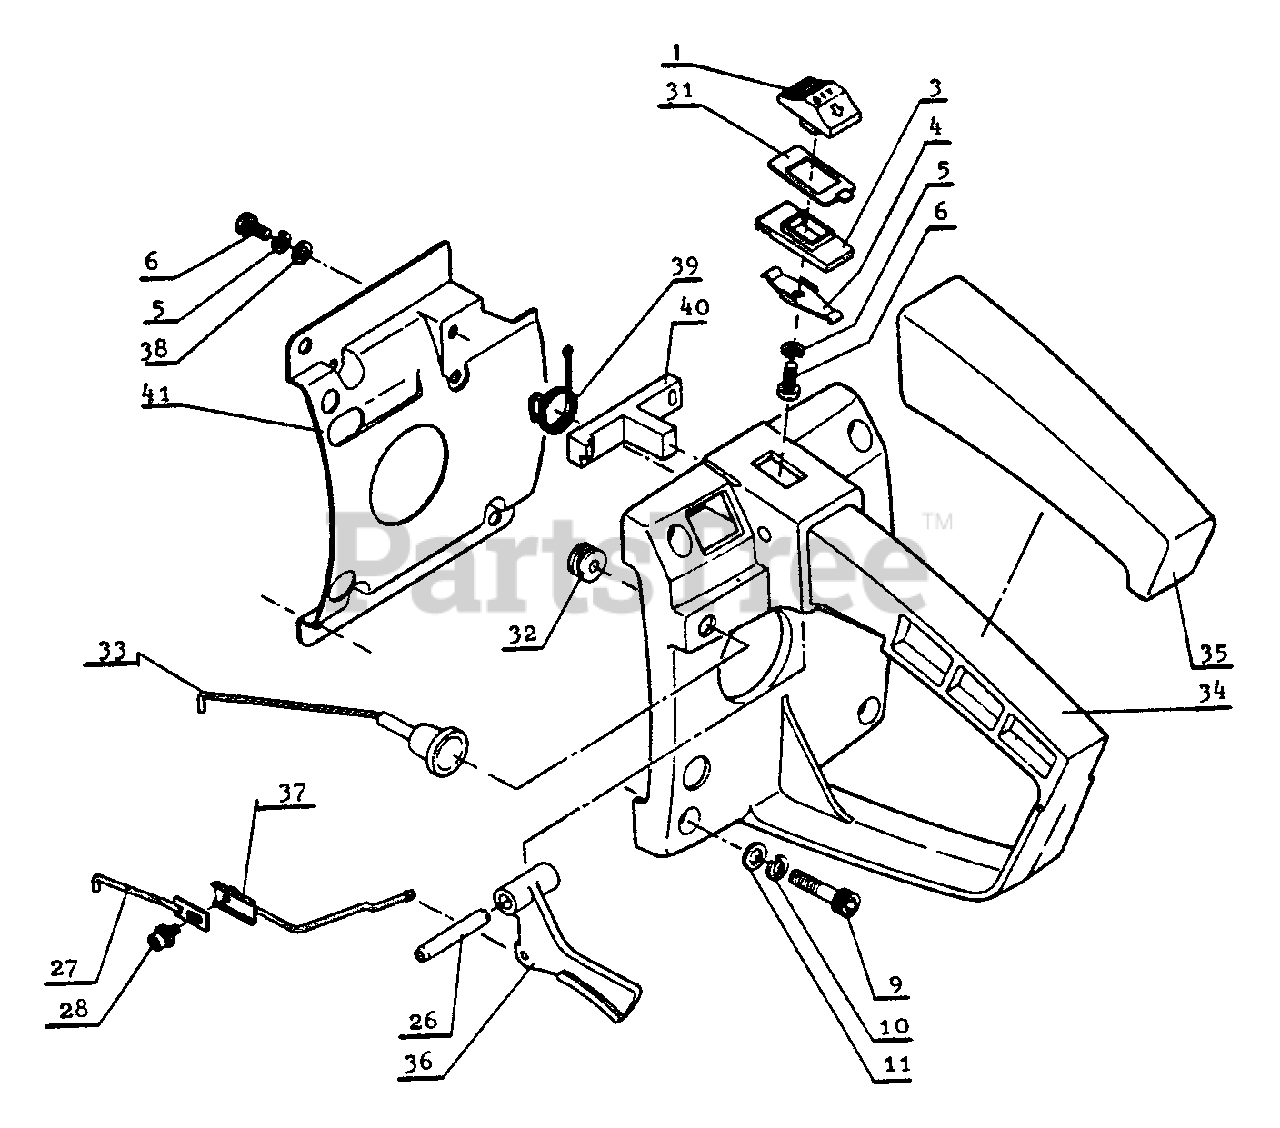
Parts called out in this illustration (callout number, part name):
1	KNOB, SWITCH
3	GUIDE, SWITCH
4	CONTACT, SWITCH
5	LOCKWASHER - 4
6	SCREW - 4X10
9	SCREW - 5X20
10	LOCKWASHER - 5
11	WASHER - 5
26	PIN
27	ROD, THROTTLE - B
28	SCREW - 3X6
31	PLATE - GROUND
32	GROMMET
33	ROD, CHOKE
34	HANDLE - REAR
35	HANDLE - REAR
36	TRIGGER, THROTTLE
37	ROD, THROTTLE - A
38	WASHER - 4
39	SPRING
40	LEVER, DECOMPRESSION
41	COVER, ENGINE
